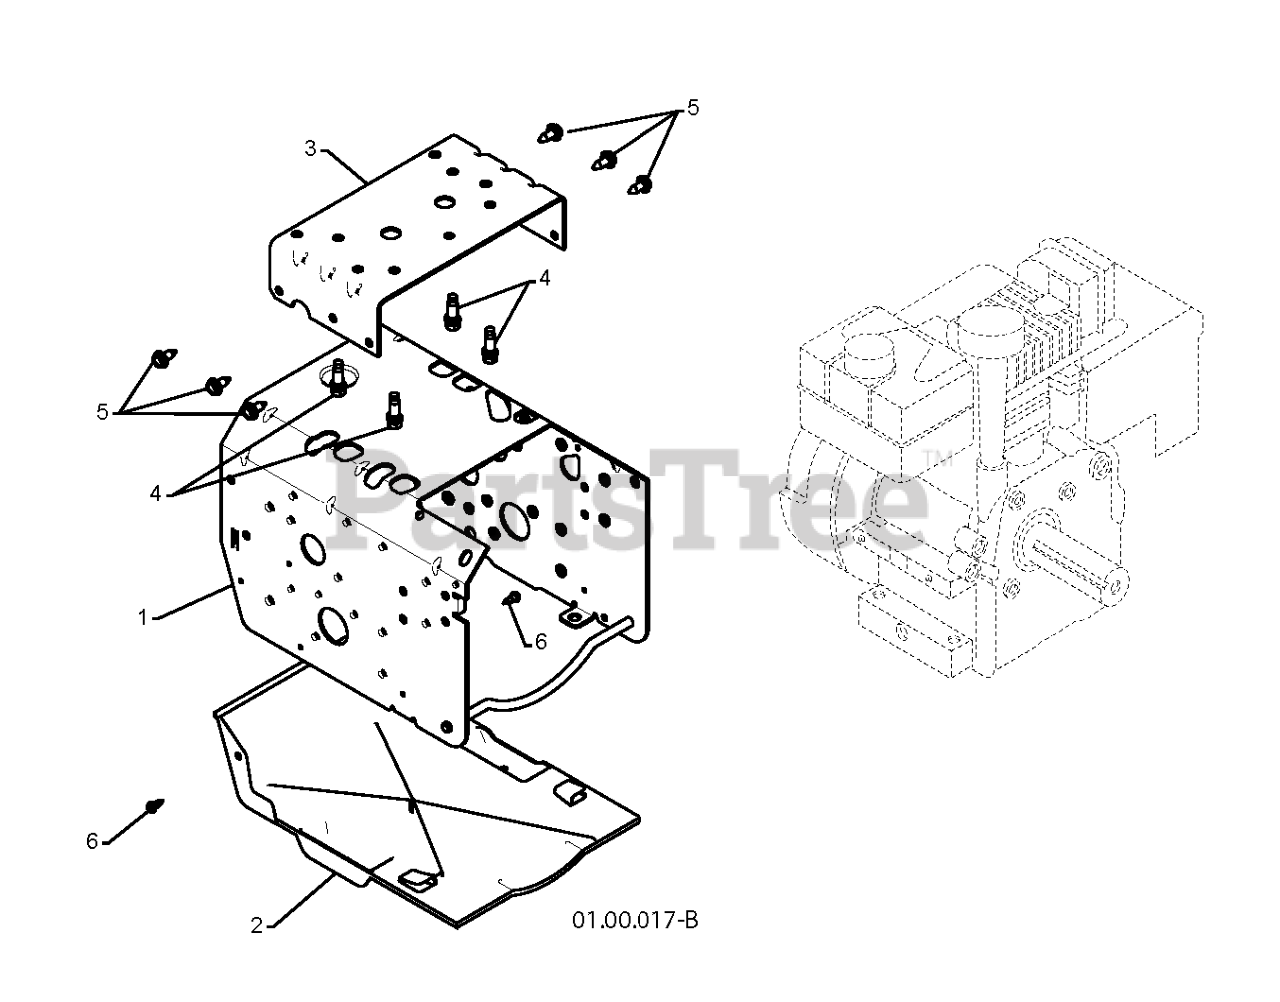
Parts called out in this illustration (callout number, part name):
2	PAN.BOTTOM.PLASTIC
4	BOLT 3/8-16X1-1/8
5	SELF-TAPPING SCREW 5/16-18X3/4
6	SCREW, HEX HEAD, TAPPING
